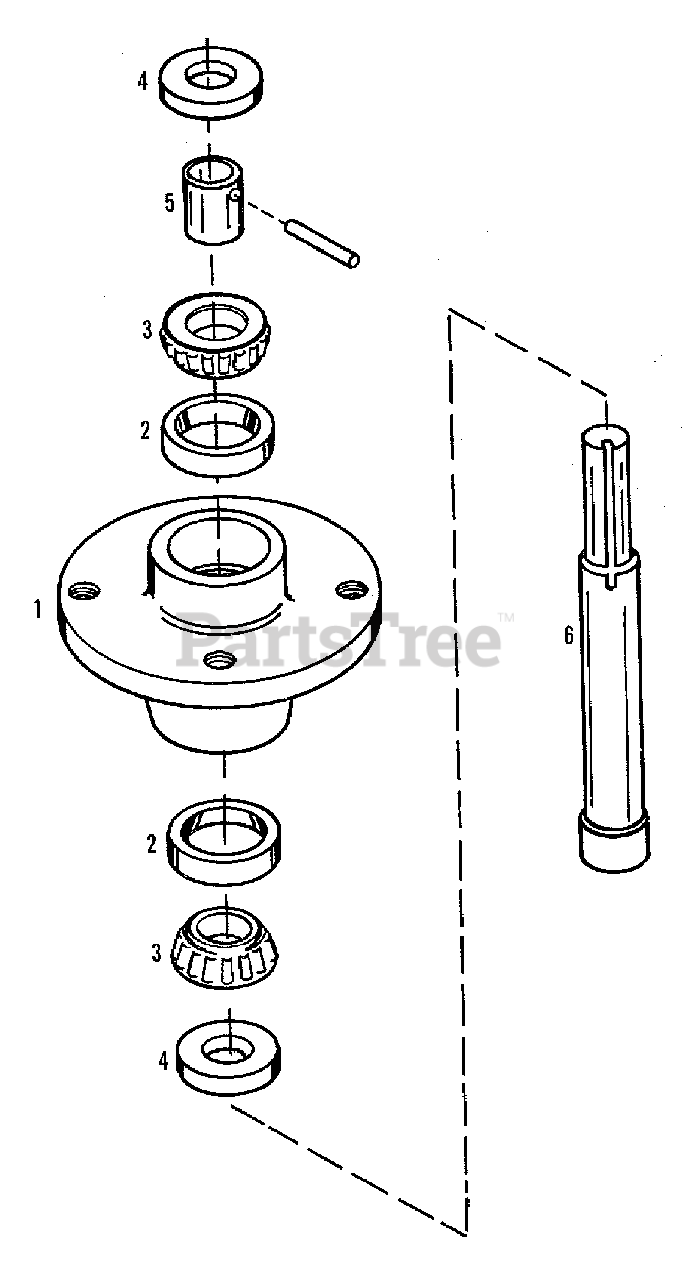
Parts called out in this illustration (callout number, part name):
1	FITTING, Lube, 1/4 Straight
2	CUP, Bearing
3	CONE, Bearing
5	PIN, Roll, 3/8 x 1-1/4
